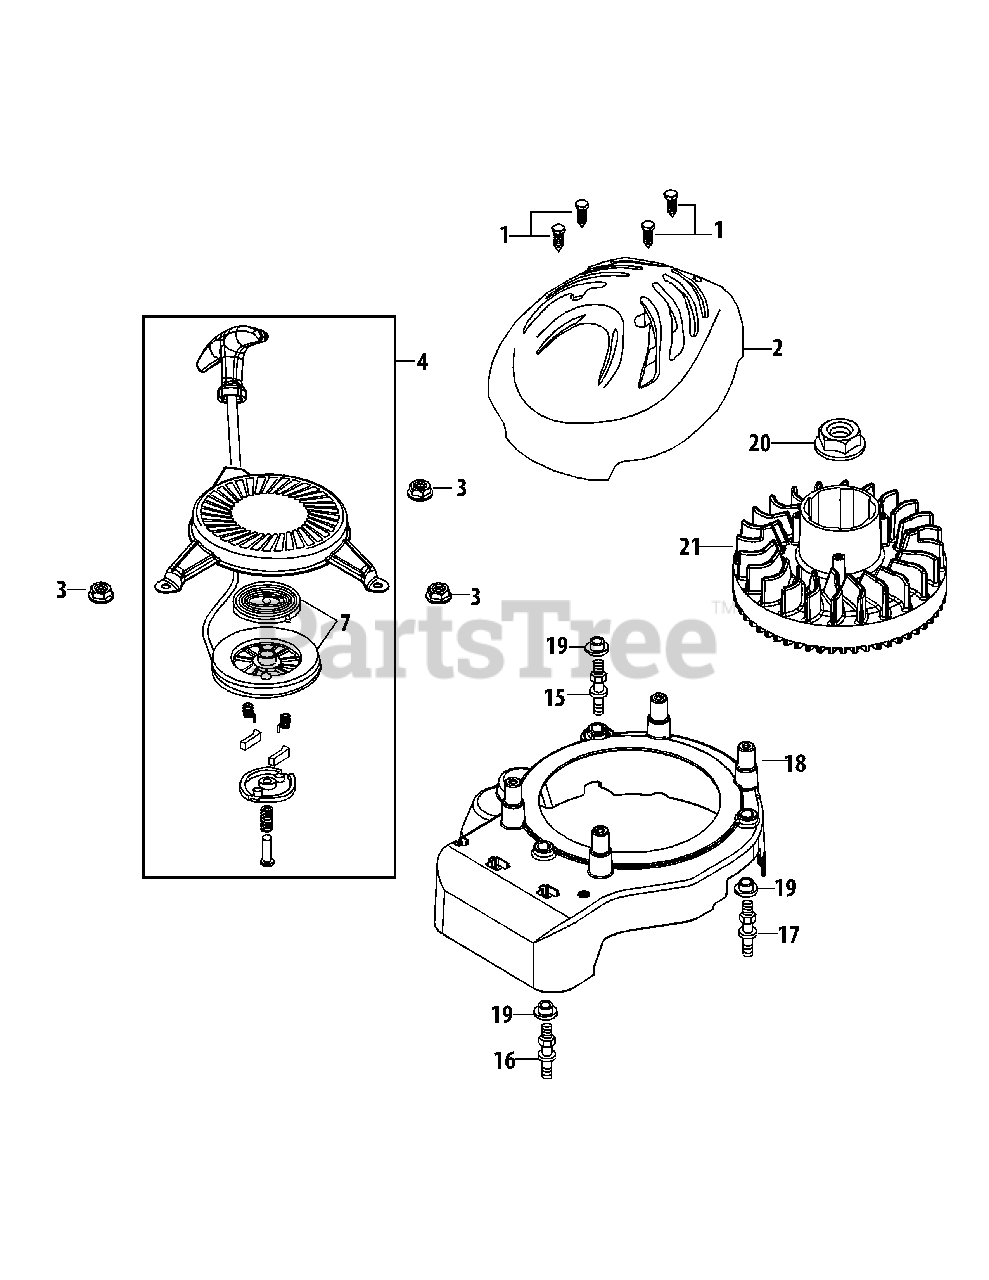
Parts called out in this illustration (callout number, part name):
1	Self-Tapping Bolt, Hilo #12-16 X 1.00"
2	Outer Shroud (Application Specific)
3	Nut M6X10Mm
4	Recoil Starter Assembly
7	Recoil Spring And Pulley Ass'Y
15	Stud Left/Black/Wh Zinc
16	Stud Front/Unmarked/Wh Zinc
17	Stud Right/White/Wh Zinc
18	Inner Shroud
19	Engine Shroud Spacer
20	Flywheel Nut M14
